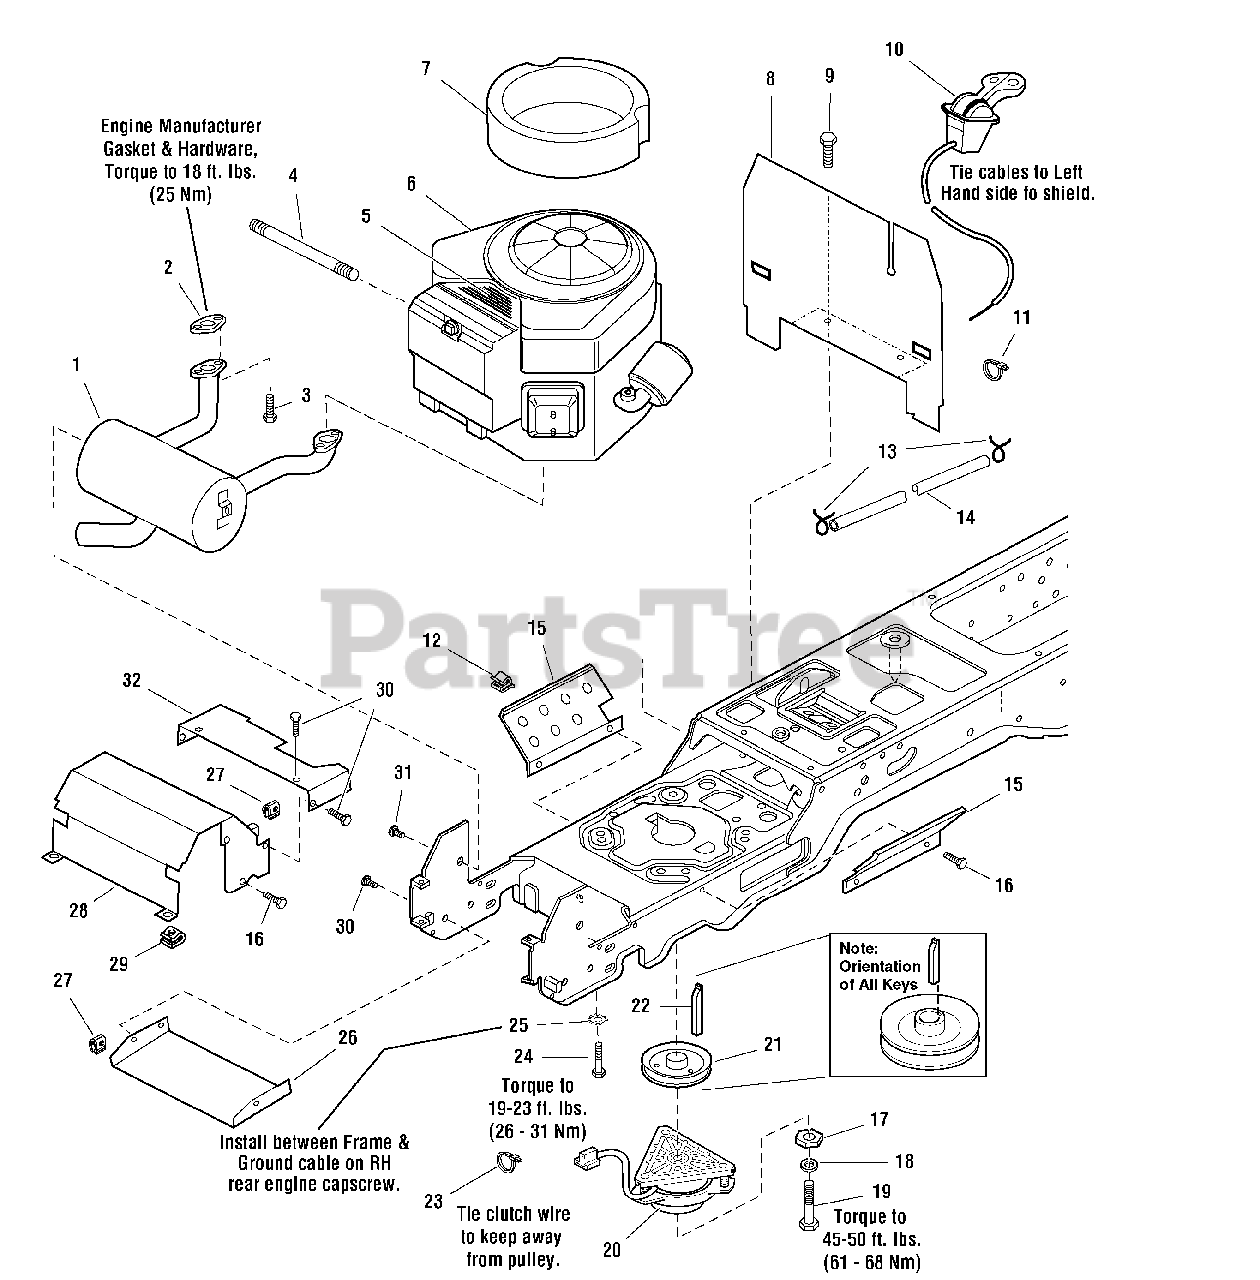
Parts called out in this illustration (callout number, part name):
1	MUFFLER
3	CAPSCREW, Socket Head, 5/16-18 x 7/8, G8
4	HOSE, Oil Drain, 6.5 inches
7	SEAL, Circle
8	BULKHEAD
9	CAPSCREW, Hex Head Taptite, 1/4-20 x 1/2
10	CONTROL, Throttle Double 39" Long w/Knobs
11	TIE
12	CLIP, Wire
13	CLAMP, Hose Type E
14	HOSE, 58" Long
15	SHIELD
16	SCREW, Hex Head Taptite, 1/4-20 x 3/8
17	WASHER, Hex
18	LOCKWASHER, 7/16
19	CAPSCREW, Hex Head, 7/16-20 x 2-3/4
20	CLUTCH, Electric, OGURA
21	PULLEY & HUB ASSEMBLY, 4-1/2 OD
22	KEY
23	TIE
24	CAPSCREW, Hex Head Taptite, 3/8-16 x 1-1/2
25	LOCKWASHER, External Tooth, 3/8
26	SHIELD, Muffler Bottom
27	NUT, Speed,1/4-20
28	DUCT, Muffler Top
29	NUT, Speed, 5/16-18
30	CAPSCREW, Hex Head Flange Lock1/4-20 x 5/8
31	CAPSCREW, Hex Head Taptite, 5/16-18 x 1/2
32	DUCT, Muffler Extension
